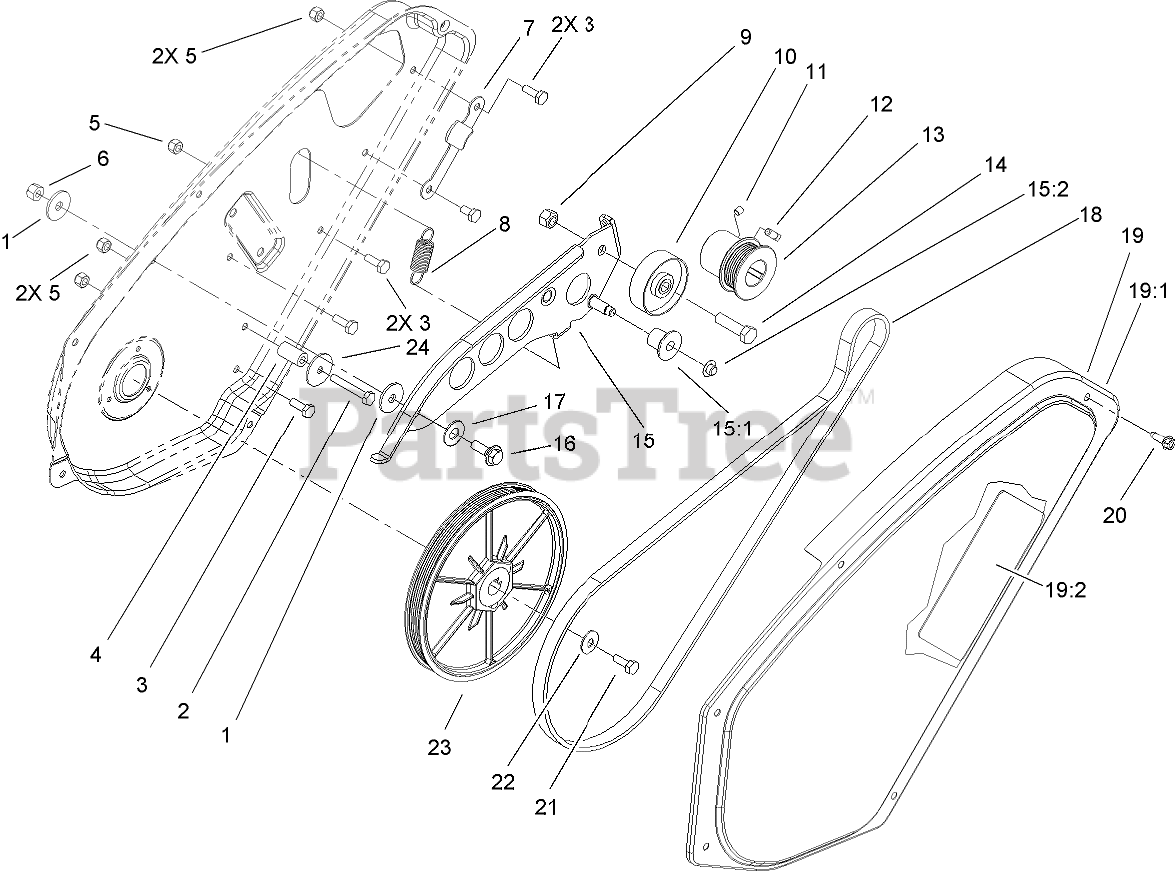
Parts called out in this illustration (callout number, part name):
1	WASHER-PIVOT
2	SCREW-HH
3	SCREW-HH
4	SLEEVE-GUIDE, BELT
5	NUT-LOCK, NI
6	NUT-LOCK, NI
7	BELT-GUIDE
8	SPRING
9	NUT-LOCK, CONE
10	PULLEY-IDLER
11	SCREW-HSH
12	SCREW-SQH
13	PULLEY
14	SCREW-HH
15	BRAKE-ARM
15:1	ROLLER-BRAKE
15:2	NUT-PUSH
16	SCREW-SHOULDER
17	WASHER
18	BELT-DRIVE
19	DRIVE COVER ASM
19:1	DECAL-WARNING
19:2	DECAL-ROUTING, BELT
20	SCREW-HWHTF
21	SCREW-HH
22	WASHER-BELLEVILLE
23	PULLEY-ROTOR
24	WASHER-FLAT
